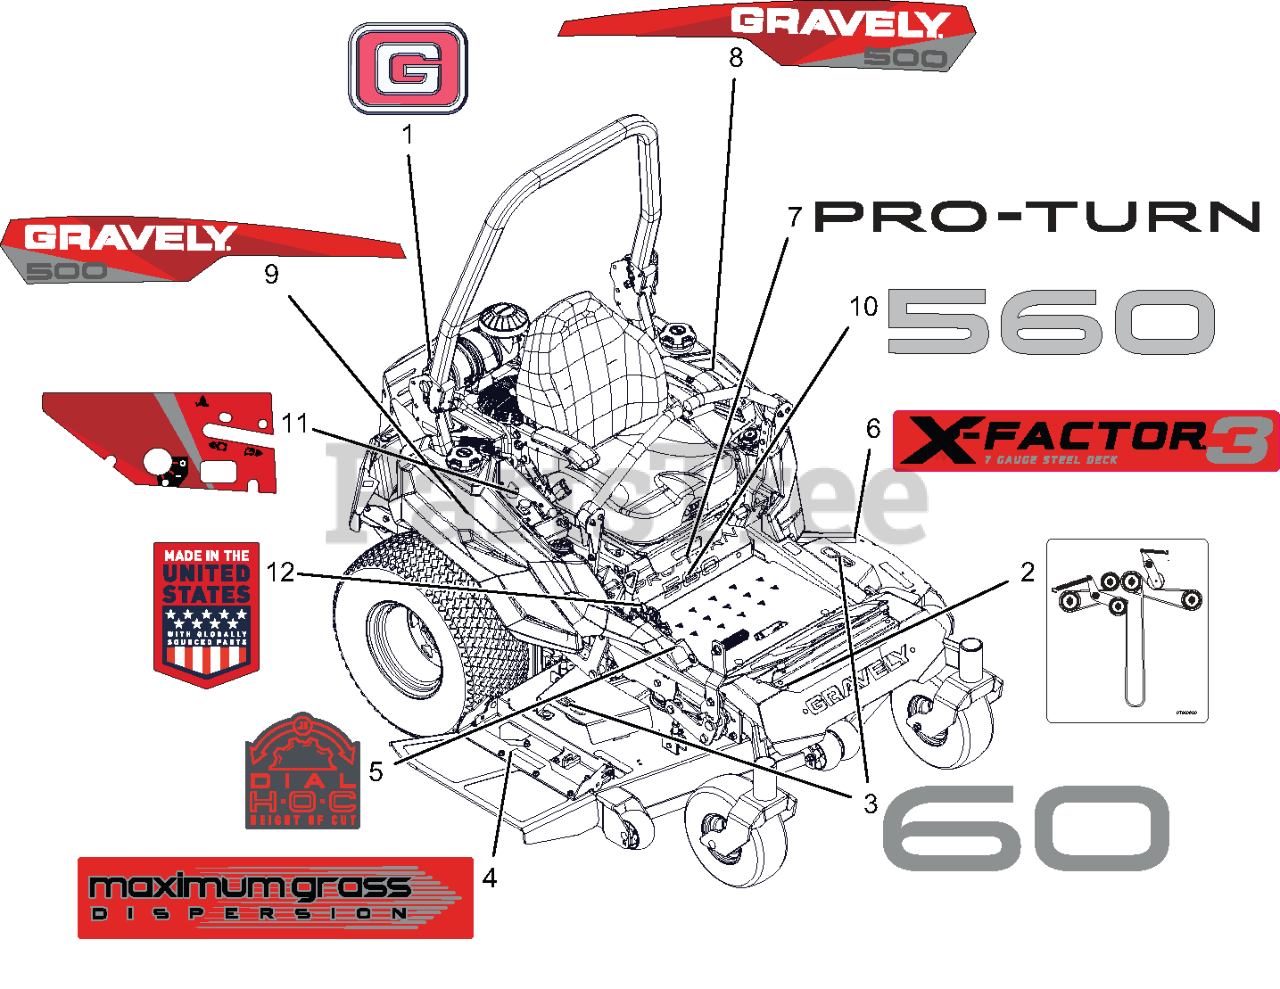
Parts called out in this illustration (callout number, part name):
1	DECAL, GRAVELY BRAND
2	DCL,BELT ROUTE-RH BK-SIDE IDLR
3	DECAL, DECK - 60
4	DECAL, DECK - MAX GRASS
5	DECAL, COVER - HOC
6	DECAL, DECK - X-FACTOR 3
7	DECAL, PRO TURN
8	DECAL- GRAVELY TANK - LH PT500
9	DECAL- GRAVELY TANK - RH PT500
10	DECAL- 560
11	DECAL- CONTROL PANEL
12	DECAL- MADE IN USA
